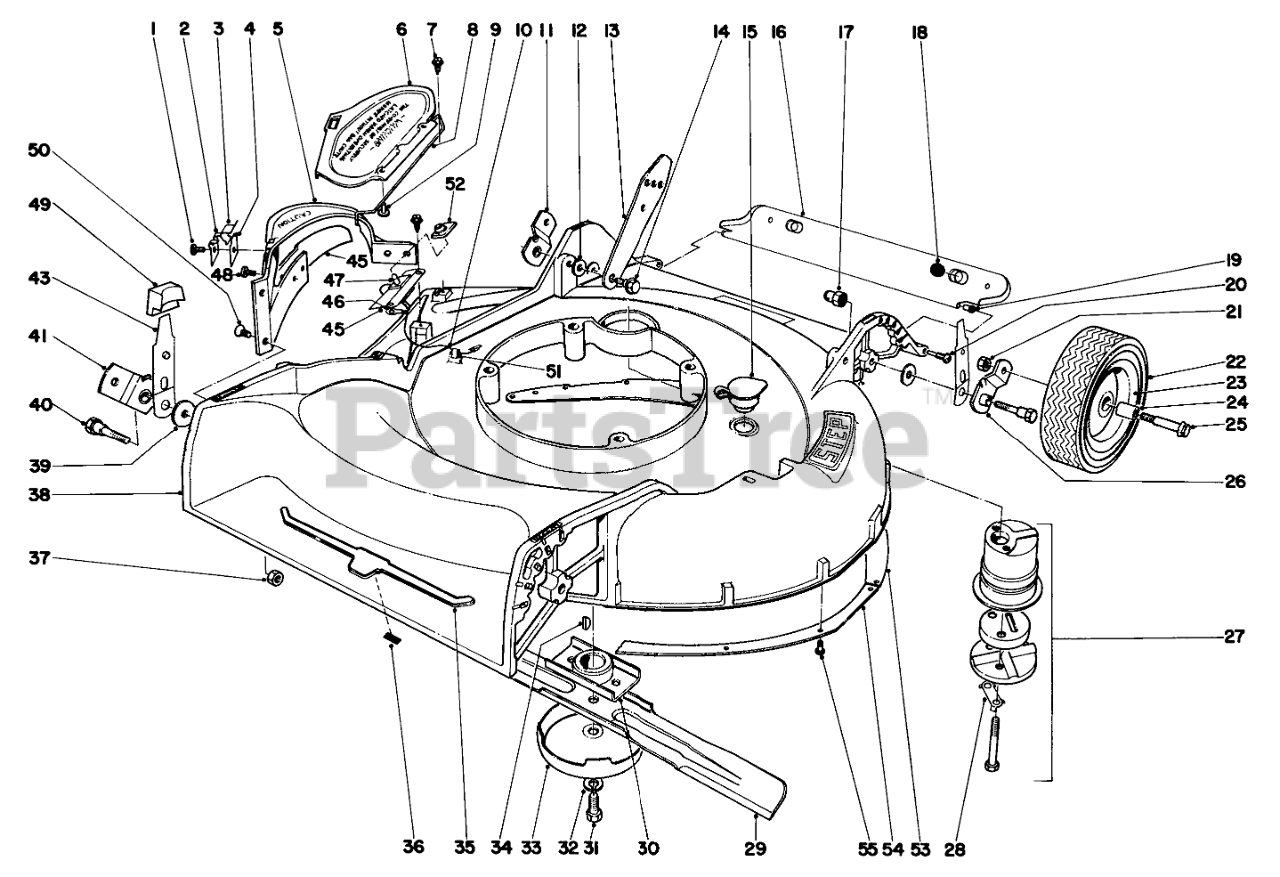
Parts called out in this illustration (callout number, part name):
2	Lower Clip
3	Upper Clip
4	Wear Plate
5	Deflector
6	Deflector (Incl. Ref. #8 & #9)
7	SCREW-HWHTF
8	Hinge Pin
9	Rivet
10	Lead Wire
11	Pivot Arm
12	SPACER
13	Handle Latch
14	SCREW-SHOULDER
15	WASHOUT PLUG
16	Safety Shield (Incl. #18 & #19)
17	Nut
18	SKID BUTTON
19	SAFTEY SHIELD BUSHING
20	SAFTEY SHIELD SCREW
21	Nut
22	8 TIRE
23	Wheel (Incl. Ref. 24)
24	Bushing
26	Pivot Arm
27	Muffler
28	CLIP - LOCKING
29	Blade
30	BLADE RETAINER WA
31	SPECIAL SCREW
32	WASHER-LOCK
33	AntiScalp Cup
34	KEY-WOODRUFF
35	Emblem, Bullshead
37	Nut
38	Housing (Incl.Ref. #53 & #55)
39	WASHER-PIVOT
40	5/16-18 PIVOT SCREW
41	Pivot Arm
43	Spring Arm
44	Mounting Plate
45	DefIector Bar
46	Ground Wire
47	Switch
49	Knob
50	Screw
52	Boot Switch
53	Main Skirt
54	Secondary Skirt
